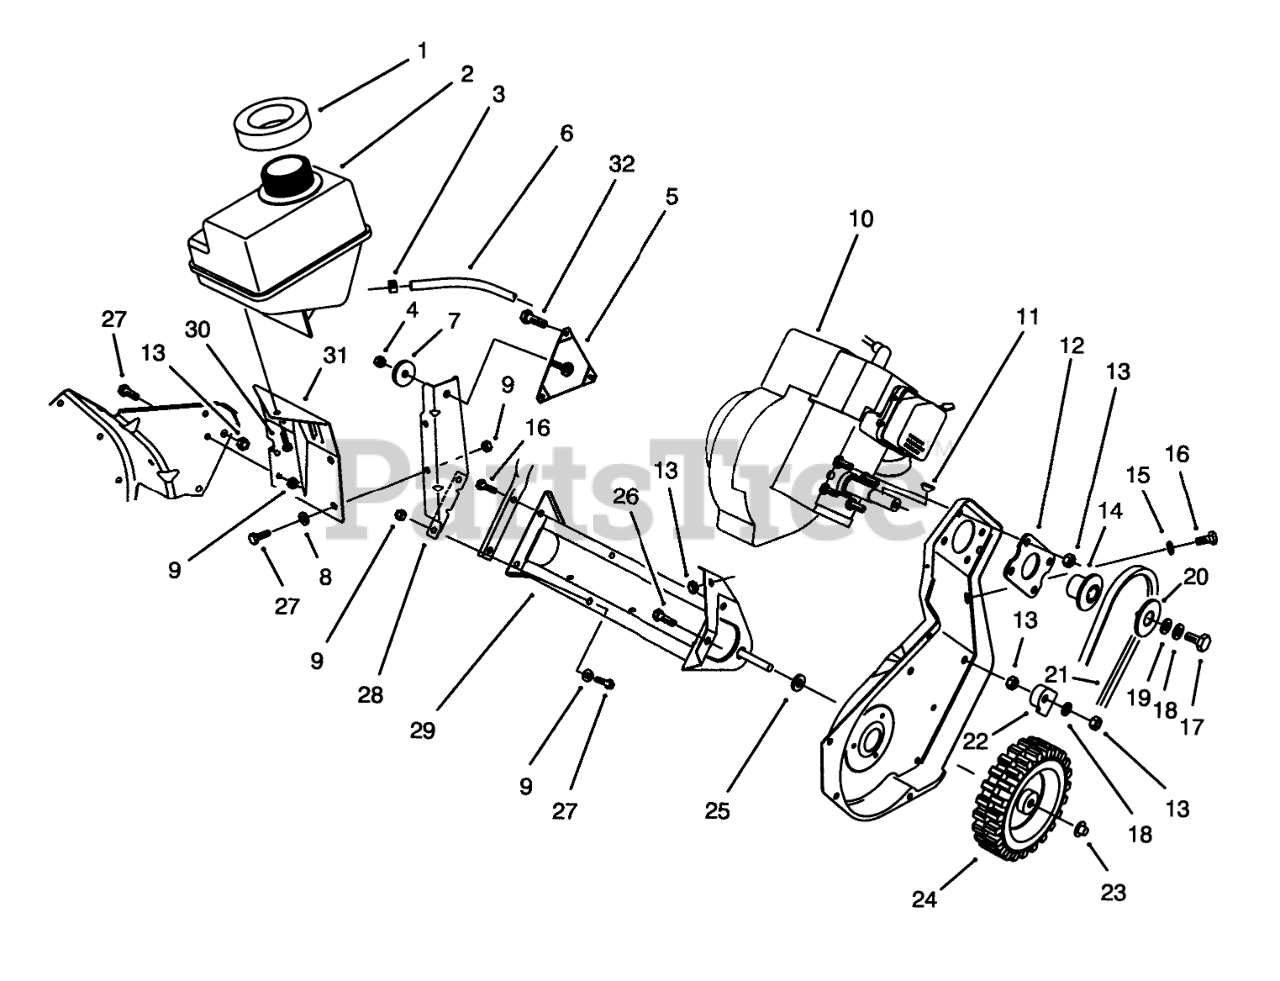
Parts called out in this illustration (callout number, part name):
1	SEAL-FOAM
2	Tank-Gas
3	Clamp
4	NUT-LOCK, NI
5	BRACKET AND STUD ASM
6	LINE-FUEL
7	WASHER-SUPPORT, ENGINE
8	WASHER-FLAT
9	NUT-LOCK, NI
11	KEY-WOODRUFF
12	Plate Engine
13	NUT-LOCK, NI
14	Hub-HALF SHEAVE
15	WASHER-PLAIN
16	SCREW-HH
17	SCREW-HH
18	WASHER-BELLEVILLE
19	WASHER-FLAT
20	CAP-HALF SHEAVE
21	V-BELT
22	GUIDE-CABLE
23	RETAINER-PUSH ON
24	WHEEL
25	SPACER-PLASTIC
26	SCREW-HH
27	SCREW-HH
28	Support-Engine
29	Frame Assembly
30	SCREW-SHWH, THREAD FORMING
31	Bracket-Fuel Tank
32	SCREW X
